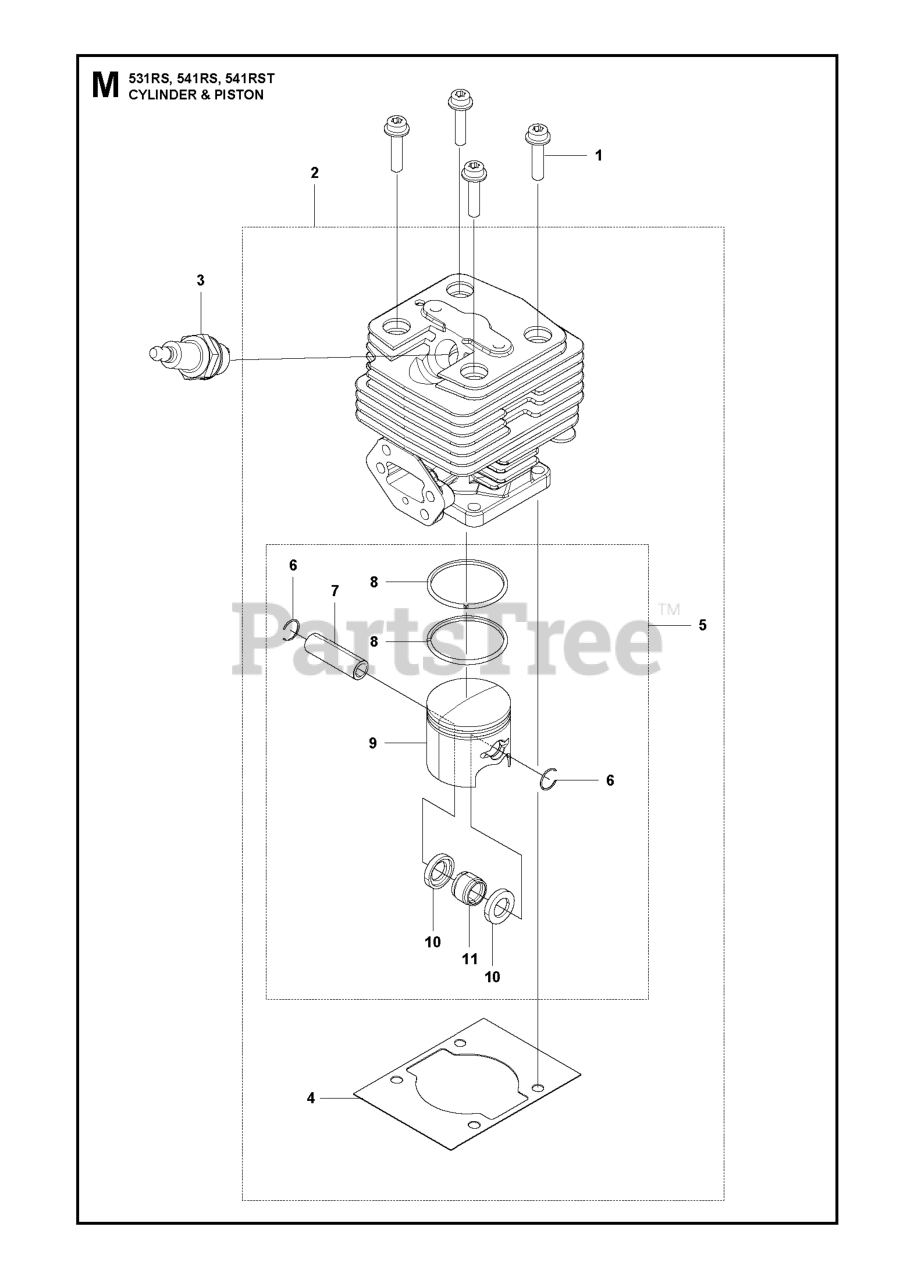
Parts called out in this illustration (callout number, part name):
7	PIN
8	PISTON RING
9	PISTON
11	ROLLER BEARING
